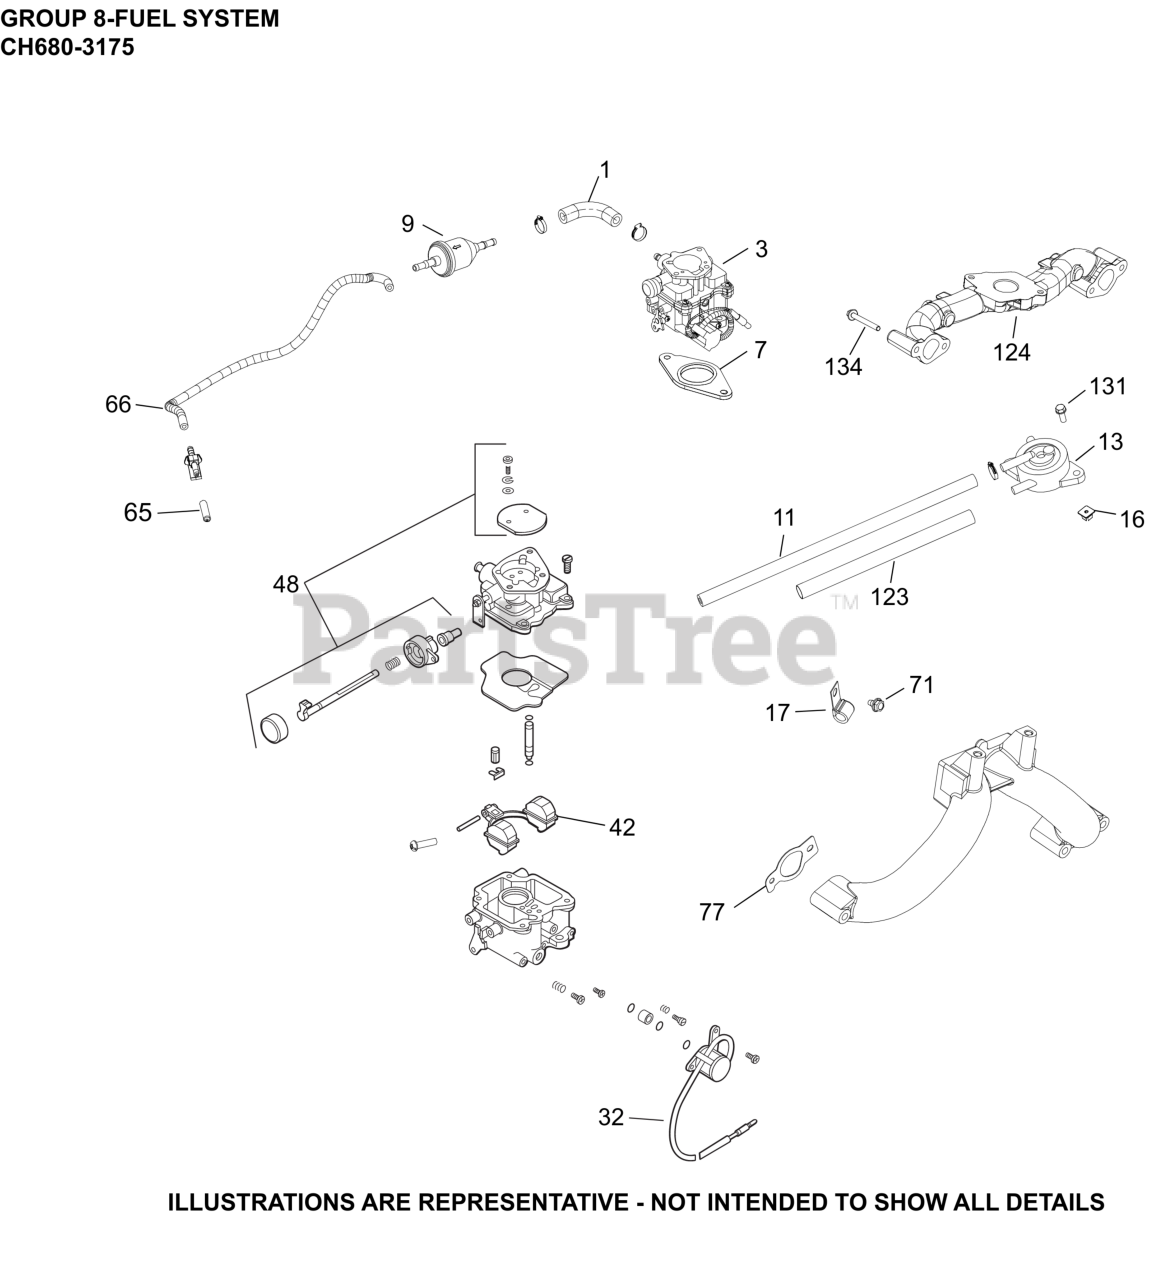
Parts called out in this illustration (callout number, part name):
1	HOSE,LW PERM.FUEL 24.00"-USE 25 111 81-S
3	KIT, CARBURETOR COMPLETE
7	GASKET, CARBURETOR
9	FILTER, FUEL
11	LINE, FLEXIBLE FUEL 15 1/2"
13	PUMP, FUEL
16	NUT, PLASTIC - BLACK
17	CLIP, CABLE (KM)
32	KIT, SOLENOID
42	KIT, REPAIR FLOAT
48	KIT, REPAIR CHOKE
65	CAP, MASKING
66	HOSE, EVAPORATIVE 20"- (#24326143S)
71	SCREW, THREAD FORMING
77	KIT, INTAKE MANIFOLD GASKET
123	SLEEVE, HEAT REFLECTIVE
124	MANIFOLD, METAL INTAKE
131	SCREW, HEX HEAD
134	SCREW, HEX FLANGE
NI	KIT, HIGH ALT (4000-8000 FT)
NI	KIT, HIGH ALT (8,000+ FT)
NI	KIT, REPAIR CARBURETOR
